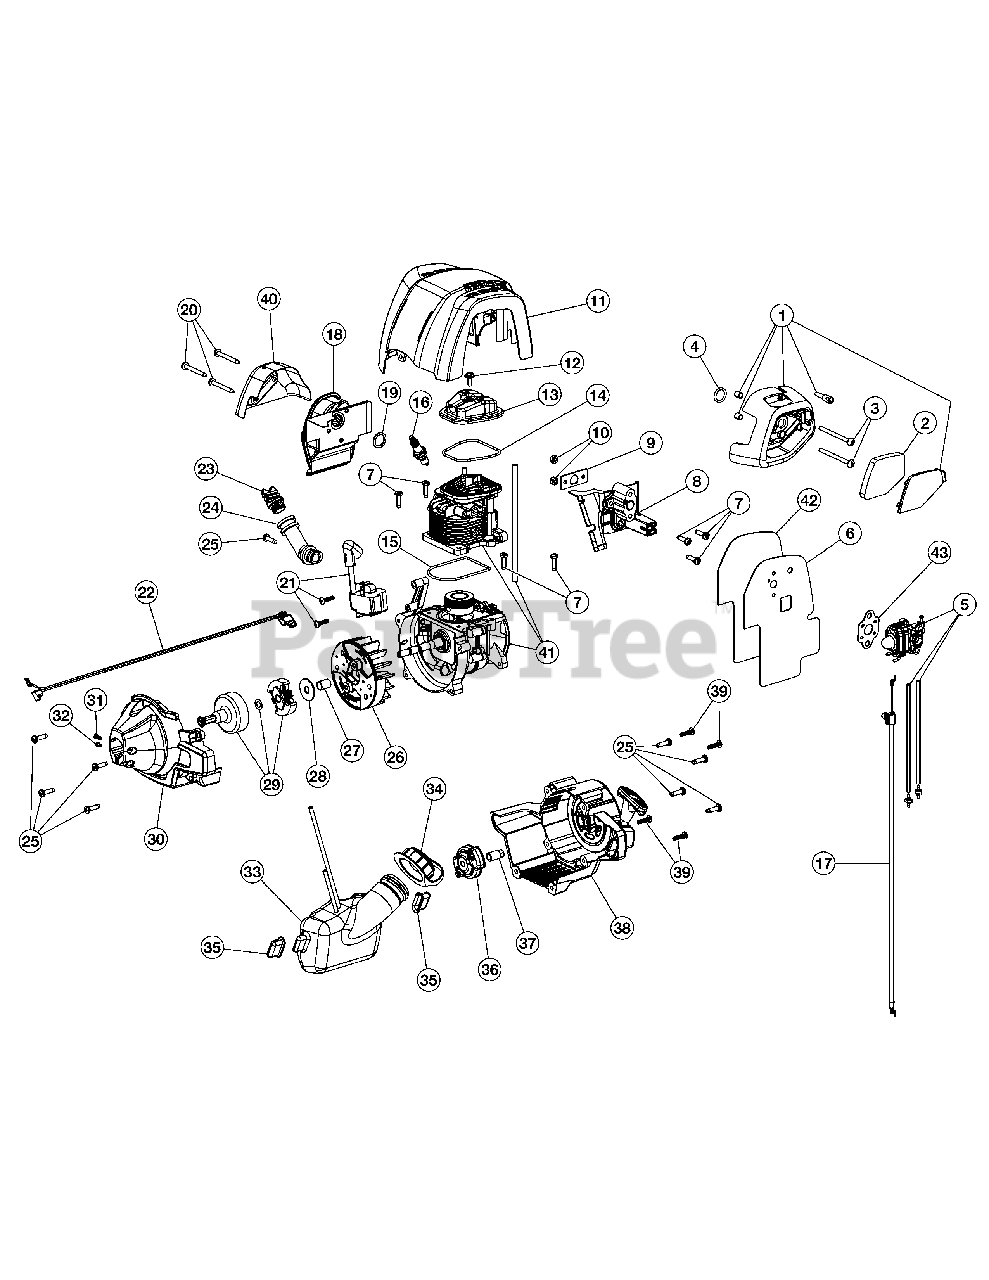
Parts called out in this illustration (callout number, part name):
1	Air Cleaner Assembly
2	Air Filter
4	Carburetor O-Ring
5	Carburetor Assembly w/Fuel Lines
6	Carburetor Baffle
7	Screw
9	Insulator Gasket
11	Engine Cover
13	Valve Cover
14	Valve O-Ring
15	Cylinder O-Ring
16	Spark Plug
17	Throttle Cable
18	Muffler Assembly
19	Muffler Gasket
20	Muffler Bolt
21	Module Assembly
22	Lead Wires
23	Oil Plug Assembly
24	Oil Fill Tube Assembly
28	Clutch Washer
29	Clutch Assembly
30	Clutch Cover Assembly
31	Anti-rotation Screw
32	Clamp Screw & Nut
35	Fuel Tank Pad
36	Pawl Assembly
37	Electric Start Adapter
38	Starter Cover Assembly
40	Muffler Shield
41	Short Block Assembly
42	Heat Shield
